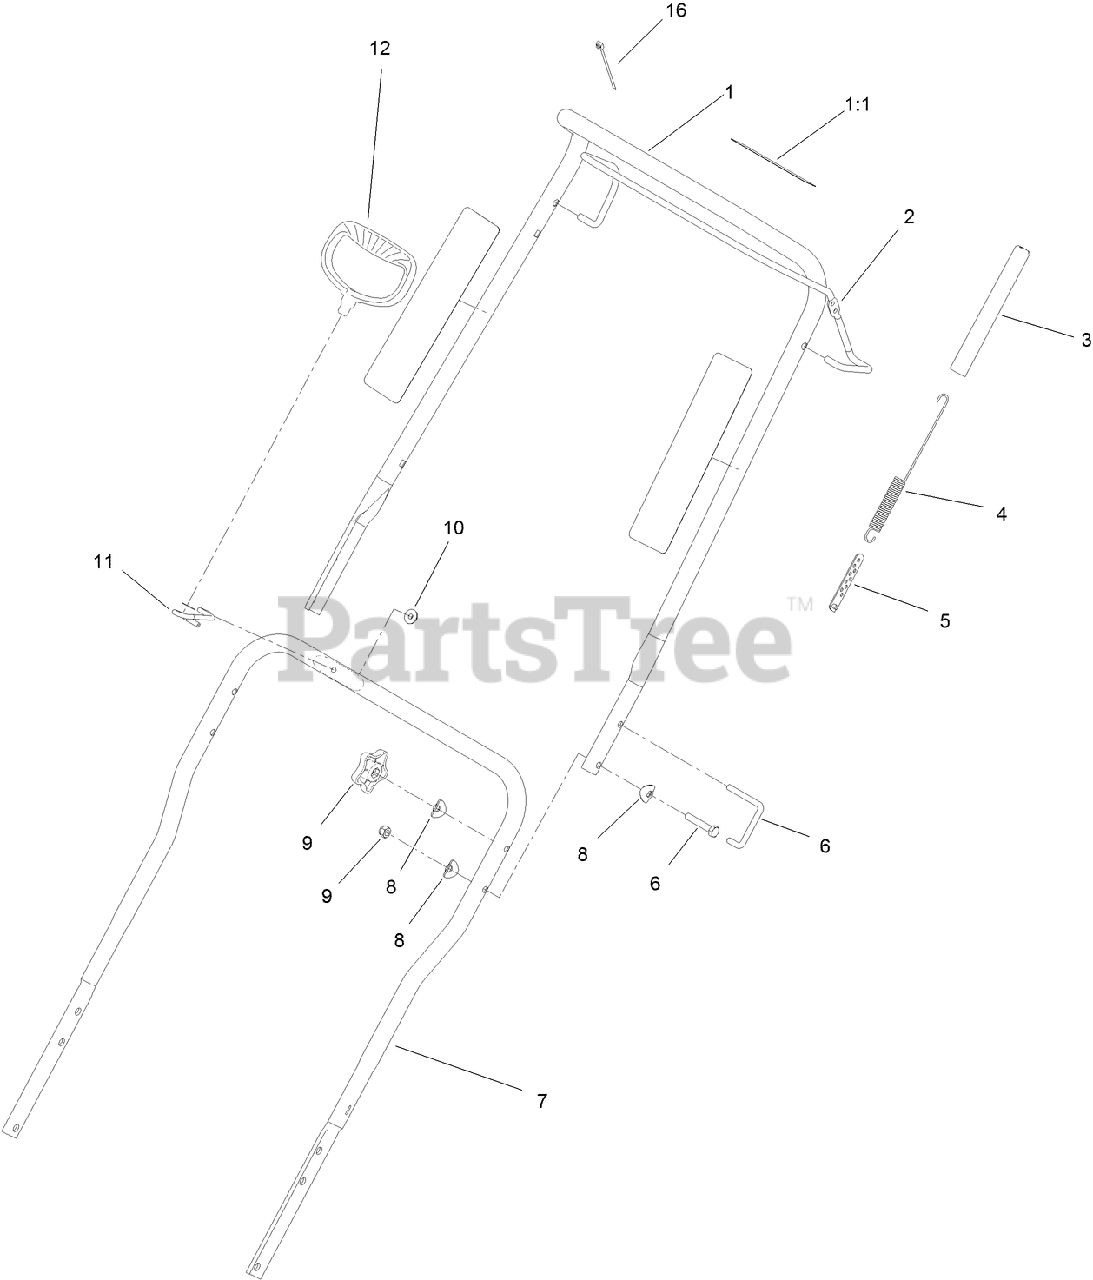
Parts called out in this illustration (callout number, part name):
1	UPPER HANDLE ASM
1:1	DECAL-DRIVE, ROTOR
2	BAIL-CLUTCH
3	COVER-SPRING
4	SPRING-EXTENSION, CLUTCH
5	ADJUSTER-CABLE, CLUTCH
6	LOCK-HANDLE
7	HANDLE-LOWER
8	WASHER
9	KNOB-HANDLE
10	NUT-HF
11	GUIDE-ROPE
12	HANDLE-RECOIL
16	TIE-CABLE
